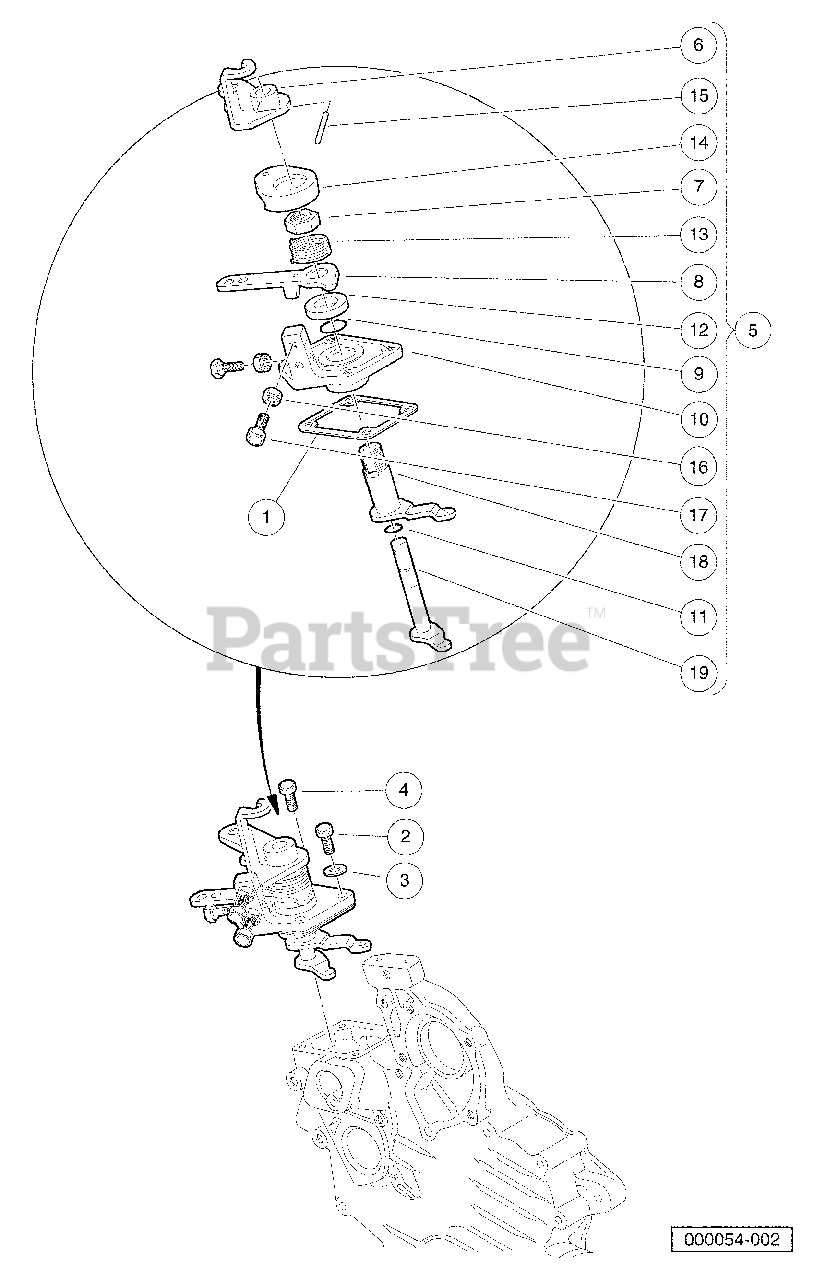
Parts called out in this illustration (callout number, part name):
1	Gasket, Control Plate.
2	Bolt, M6 X 1 X 30
3	Gasket, 6 X 10
4	Bolt, D722 Intake Manfld Lower.
5	Assembly, Speed Plate
6	Lever, Engine Stop
7	Nut, Speed Control
8	Lever, Speed Control.
9	O Ring, 19 X 16
10	Plate, Speed Control.
11	O Ring, 9 X 7
12	Collar, Lever.
13	Spring, Return.
14	Cap, Speed Cntrl Plate Rtrn
15	Pin, Spring, Speed Plate
16	Nut, Speed Control
17	Bolt, Speed Control.
18	Lever, Governor
19	Shaft, Governor Lever
